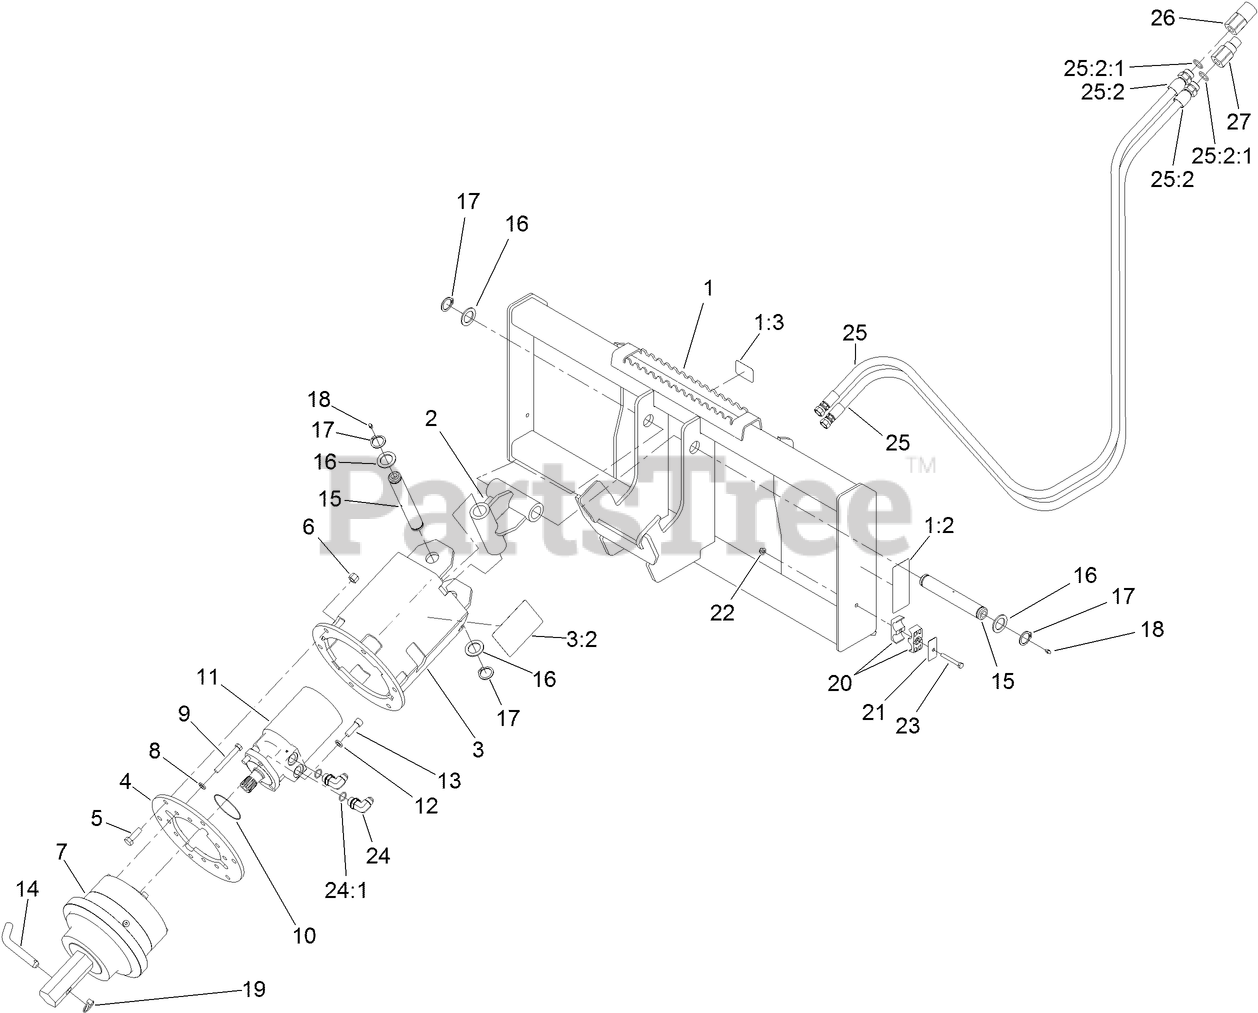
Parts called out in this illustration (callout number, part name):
1	AUGER MOUNT ASM
1:2	DECAL-WARNING
1:3	DECAL
2	ADAPTER-PIVOT
3	PLANETARY MOUNT ASM
3:2	DECAL-WARNING
4	PLATE-PLANETARY
5	SCREW-HH
6	NUT-LOCK, NI
7	DRIVE-PLANETARY
8	SCREW-HH
9	SCREW-HH
10	GASKET-SEAL
11	MOTOR-HYD
12	SCREW-HH
13	SCREW-HSH
15	PIN-PIVOT
16	WASHER-STEERING
17	RING-RETAINING, EXTERNAL
18	FITTING-ZERK
19	PIN-LOCK
20	CLAMP-TUBE
21	PLATE-COVER
22	NUT-HF, NI
23	SCREW-HH
24	FITTING-90 DEG
24:1	O-RING
25	HYD HOSE ASM
25:2	FITTING-STRAIGHT
25:2:1	O-RING
26	FITTING-ADAPTER
27	FITTING-ADAPTER
